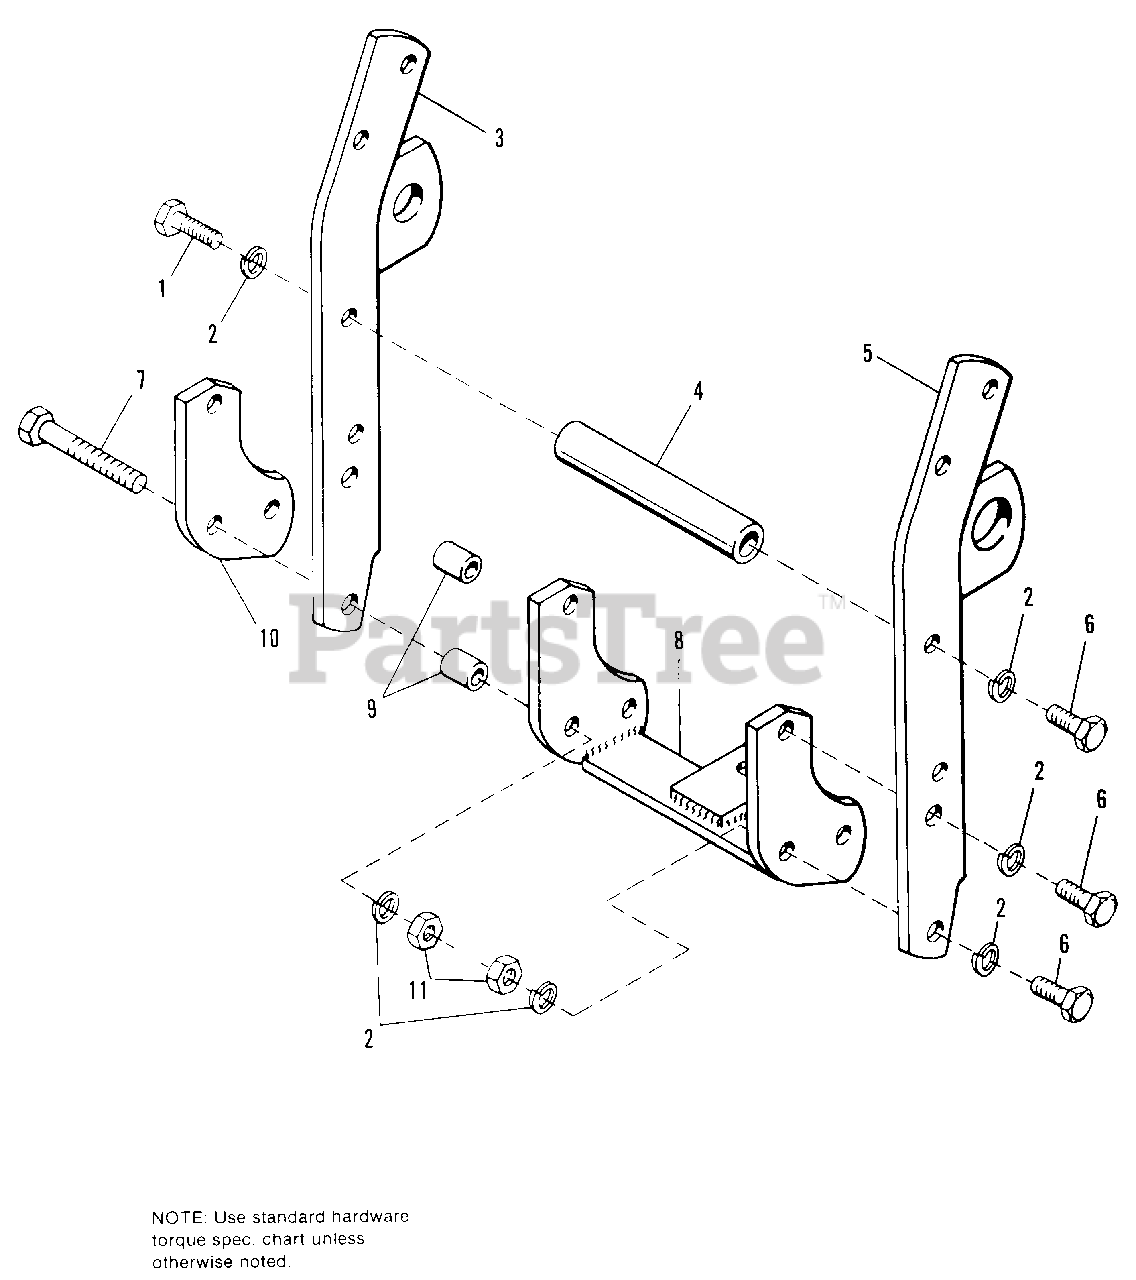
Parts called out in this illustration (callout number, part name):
1	CAPSCREW, Hex Hd., 7/16-14 x 1-3/4
2	LOCKWASHER, 7/16
3	BAR ASSY., Upright
5	BAR ASSY.,Upright
6	CAPSCREW, Hex Hd., 7/16-14 x 1-1/4
7	CAPSCREW, Hex Hd., 7/16-14 x 2-3/4
8	BAR ASSY., Draw
11	NUT, Hex, Full, 7/16-14
